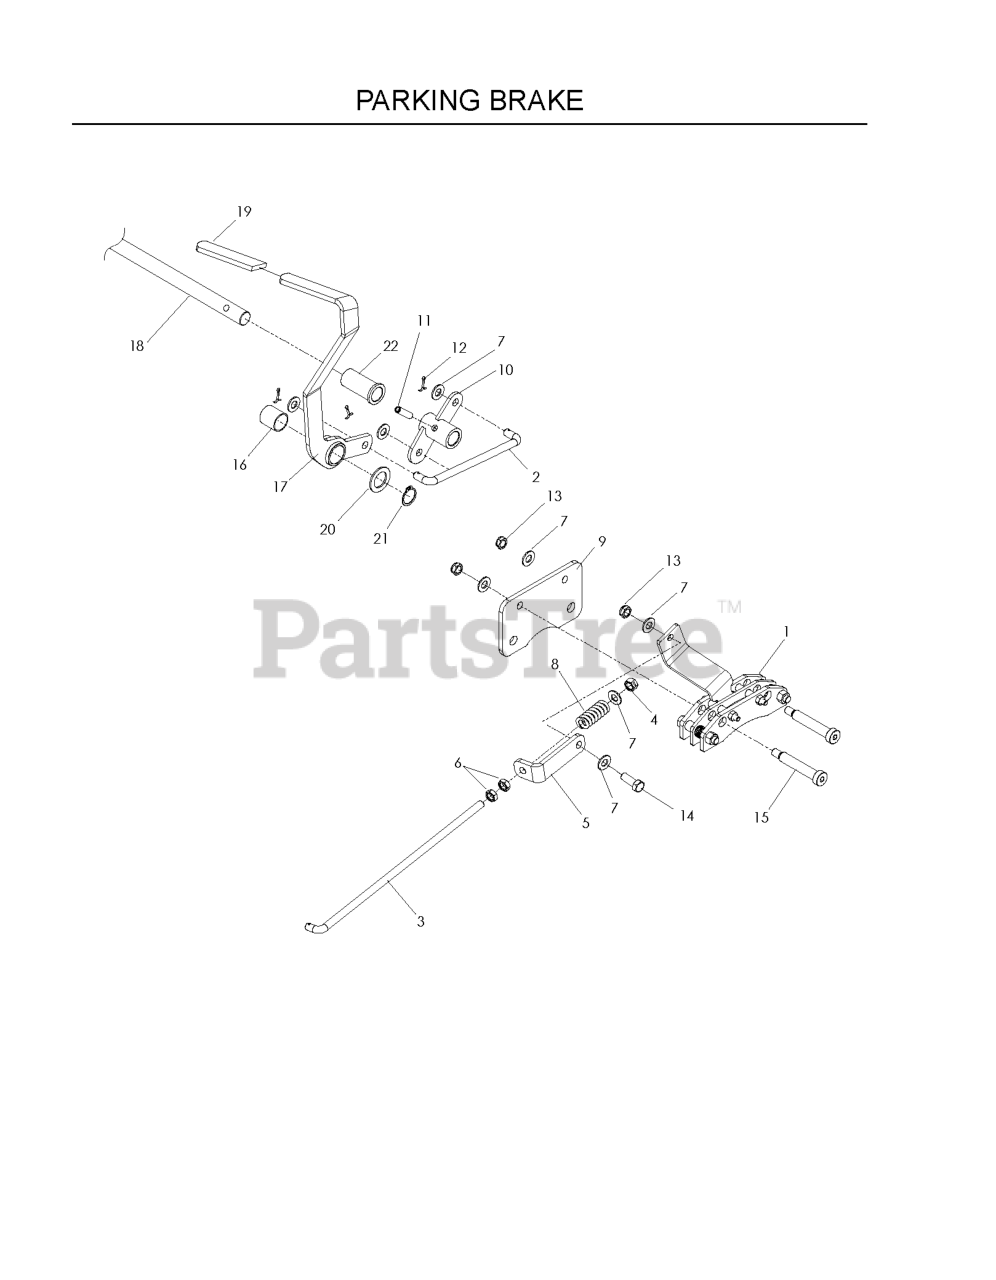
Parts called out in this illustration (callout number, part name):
2	LINKAGE, BRAKE
3	LINKAGE, REAR BRAKE
4	NUT 3/8F CENTERLOCK
5	BRACKET, L
6	NUT 3/8-24 JAM
7	WASHER 3/8 SAE FLAT
9	PLATE, BRAKE
10	BELLCRANK, BRAKE
11	5/16 DIA ROLL PIN
12	COTTER PIN 3/32 X 3/4
13	NUT HEX 3/8-16 NYLON, THIN
14	HCS 3/8-16X1.GRD.5.ZD
15	SB 3/8-16 X 2-1-1/2 SKT HDD ZD
17	BRAKE LEVER WLDMT
19	GRIP, PARK BRAKE
20	BSHG .875 X 1.375 X .074 ZD
21	RETAINING RING, 7/8"
22	BUSHING, POLYMER 3/4X2
